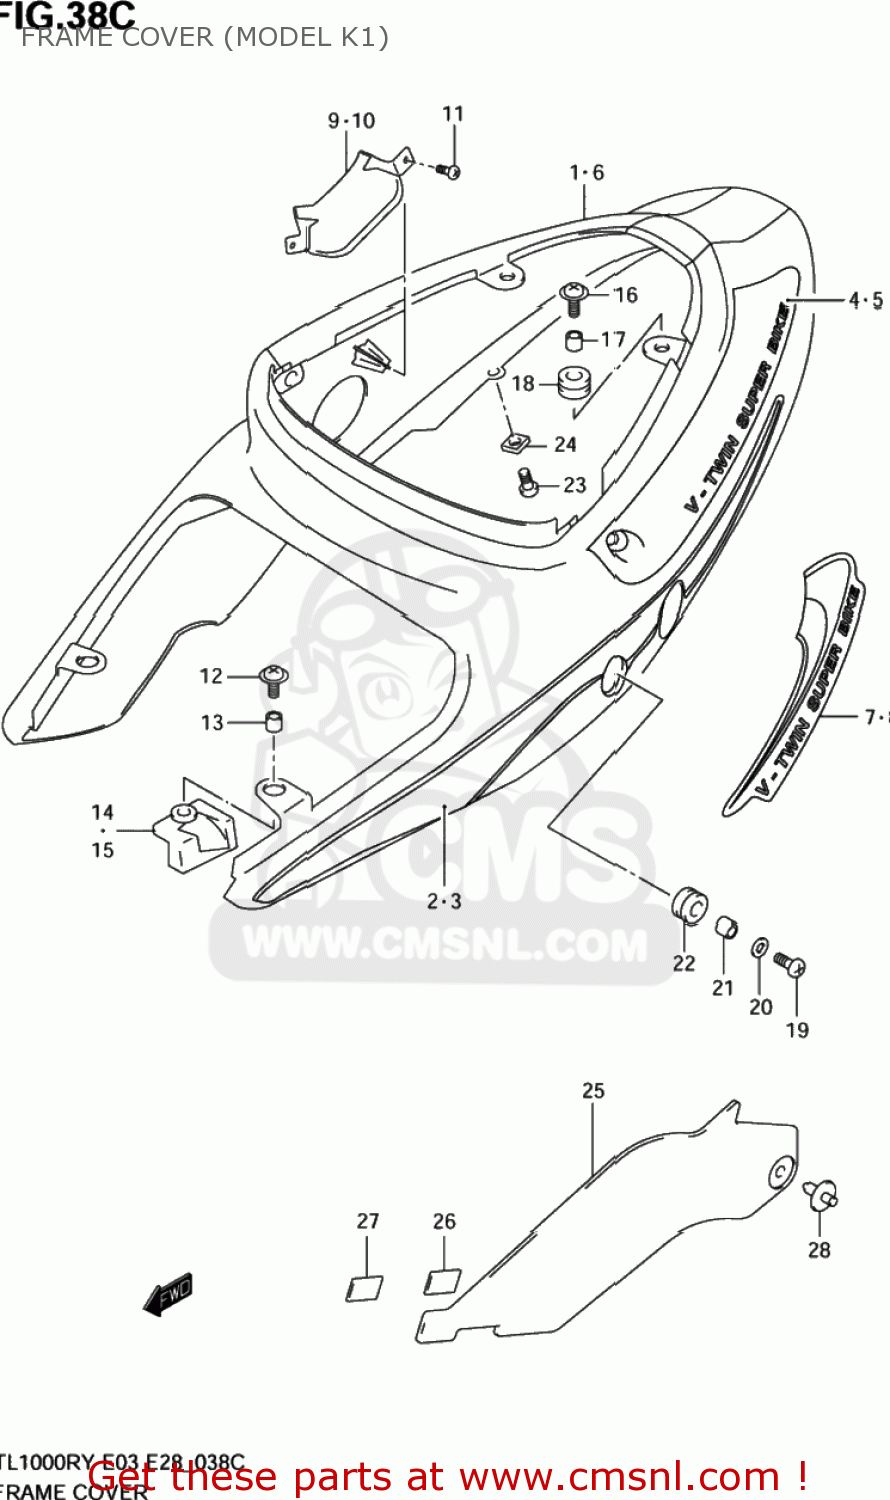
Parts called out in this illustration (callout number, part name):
1	COVER,FRAME(BLACK)
2	TAPE SET,FRAME COVER,R
3	TAPE SET, LH LOWER
4	TAPE,FRAME COVER,R
5	TAPE,FRAME COVER,L
6	COVER,FRAME(YELLOW)
7	TAPE,FRAME COVER,R
8	TAPE,FRAME COVER,L
9	CAP,FRAME COVER HOLE,R
10	CAP,FRAME COVER HOLE,L
11	SCREW
12	SCREW(6X20)
13	SPACER(6.5X9X9)
14	CUSHION,FRAME COVER,R
15	CUSHION,FRAME COVER,L
16	SCREW(6X20)
17	SPACER(6.5X10X9.4)
18	CUSHION
19	SCREW(6X20)
20	WASHER(6.5X22X1.6)
21	SPACER(6.5X9X6.7)
22	CUSHION
23	CLIP
24	NUT
25	COVER,FRAME,FRONT,RIGHT
26	FASTENER,NO.1
27	FASTENER,NO.2
28	CLIP(GRAY)
